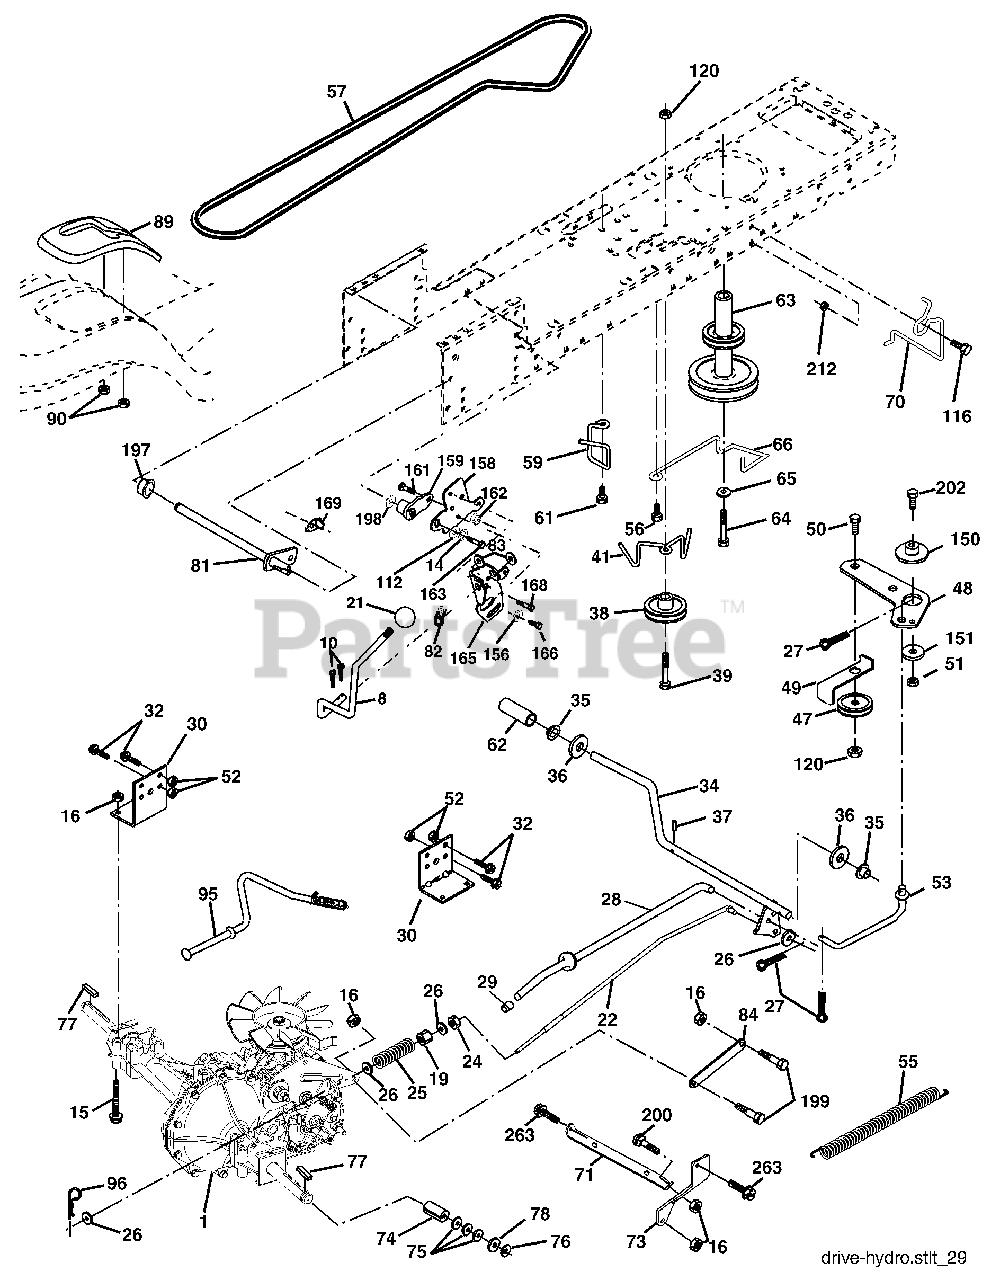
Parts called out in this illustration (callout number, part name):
1	Transmission
8	Rod, Shift
10	Pin, Cotter 1/8 x 1
14	Washer Lock 1/4
15	Bolt Hex Flghd 5/16-18 Gr. 5
16	Nut, Lock Hex w/Ins 5/16-18 unc
19	Nut Lock Hex w/Ins 3/8-16
21	Knob
22	Rod, Brake
24	Nut
25	Spring, Rod, Brake
26	Washer 13/32 x 13/16 x 16 Ga.
27	Pin, Cotter 1/8 x 3/4
28	Rod, Parking Brake
29	Cap, Parking Brake
30	Bracket, Transmission
32	Bolt Hex 5/16-18 unc x 3/4
34	Shaft, Foot Pedal
35	Bearing, Nylon
36	Washer
37	Pin, Roll
38	Pulley, Composite
39	Bolt
41	Keeper, Belt, Idler
47	Pulley, Idler, V-Belt
48	Bellcrank Clutch Grnd Drustl
49	Retainer, Belt
50	Bolt Carr. Sh 3/8-16 x 1-1/2 Gr. 5
51	Nut
52	Nut Crownlock 5/16-18
53	Link, Clutch
55	Spring, Return, Clutch
56	Screw 3/8-16 x 1-1/4
57	V-Belt, Drive
59	Keeper, Belt, Center
61	Screw 3/8-16 x .875
62	Cover, Pedal
63	Pulley, Engine
64	Bolt Hex 7/16 x 4 Gr. 5
65	Washer
66	Keeper, Belt Engine Hydro
70	Guide, Belt, Mower Drive RH
71	Strap, Torque, Lh
73	Strap, Torque, Rh
74	Spacer, Axle
75	Washer 25/32 x 1-1/4 x 16 Ga.
76	Ring, E
77	Key, Square
78	Washer 25/32 x 1-5/8 x 16 Ga.
81	Shaft Asm Cross
82	Spring, Torsion
83	Washer 17/32 x 3/4 x 16 Ga.
84	Link Transaxle
89	Console, Shift
90	Nut Self-Thd Wshd 1/4
95	Control Asm Bypass Hydro
96	Spring, Retainer 1"
112	Washer 9/32 x 3/4 x 10 Ga.
116	Bolt Rdhd Sq Neck 3/8-16 x 1
120	Nut Lock Flg 3/8-16
150	Spacer Retainer
151	Washer 13/32 x 2 x 10
156	Washer 5/16 x 1.0 x 1.25
158	Bracket Shift Mount
159	Hub Shift
161	Bolt Rdhd Sqnk 1/4-20 x 3/4 Gr. 5
162	Nut Crownlock 1/4-20 unc
163	Bolt Hex Fin 1/4-20 x 1
165	Bracket Pivot Lever
166	Screw 5/16 x 18 x 5/8
168	Bolt Shoulder 5/16-18 x .561
169	Plate Fastener Cross Shaft
197	Nyliner Snap-In
198	Washer Nyliner
199	Bolt Shoulder 5/16-18 unc
200	Bolt Rd Hd Sqnk 5/16-18 unc x 1
202	Bolt Carr. Sh 3/8-16 x 1-3/4 Gr. 5
212	Nut Hex Flange Lock
263	Screw 3/8-16 x 3/4
